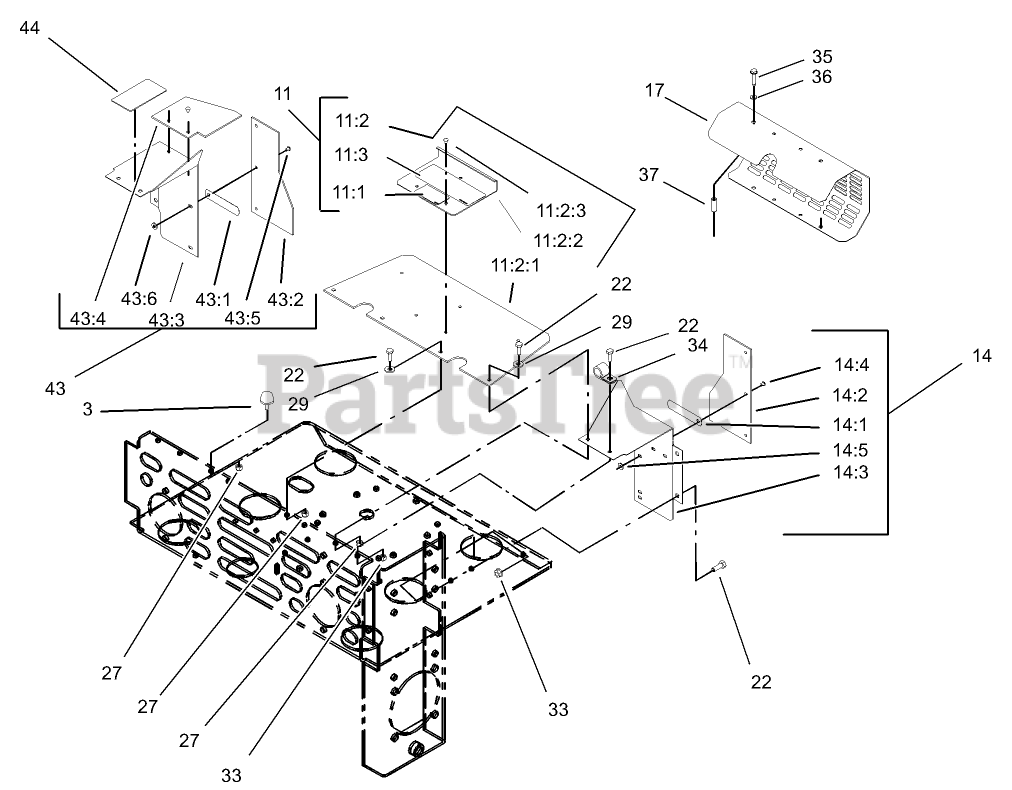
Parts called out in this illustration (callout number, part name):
3	BUMPER
11	SHIELD ASM
11:1	DECAL-IMPORTANT
11:2	SHIELD AND LIFT ASM
11:2:1	SHIELD-ENGINE
11:2:2	LIFT-SHIELD
11:2:3	RIVET-POP
11:3	DECAL-DEVICES, ROTATING
14	LH SHIELD ASM
14:1	CLIP-BAFFLE, REAR
14:2	SHIELD-ENGINE
14:3	BAFFLE-ENGINE SHIELD, LH
14:4	RIVET-POP
14:5	WASHER-FLAT
17	GUARD-MUFFLER
22	SCREW-HH
27	NUT-LOCK, NI
29	WASHER-FLAT
33	NUT-HF
34	CLIP-LOOM
36	WASHER-SPRING
37	SPACER
43	RH SHIELD ASM
43:1	CLIP-BAFFLE, REAR
43:2	SHIELD-ENGINE
43:3	SHIELD-RH
43:4	BAFFLE-COOLER, ENGINE
43:5	RIVET-POP
43:6	WASHER-FLAT
44	DECAL-ROUTING, BELT
